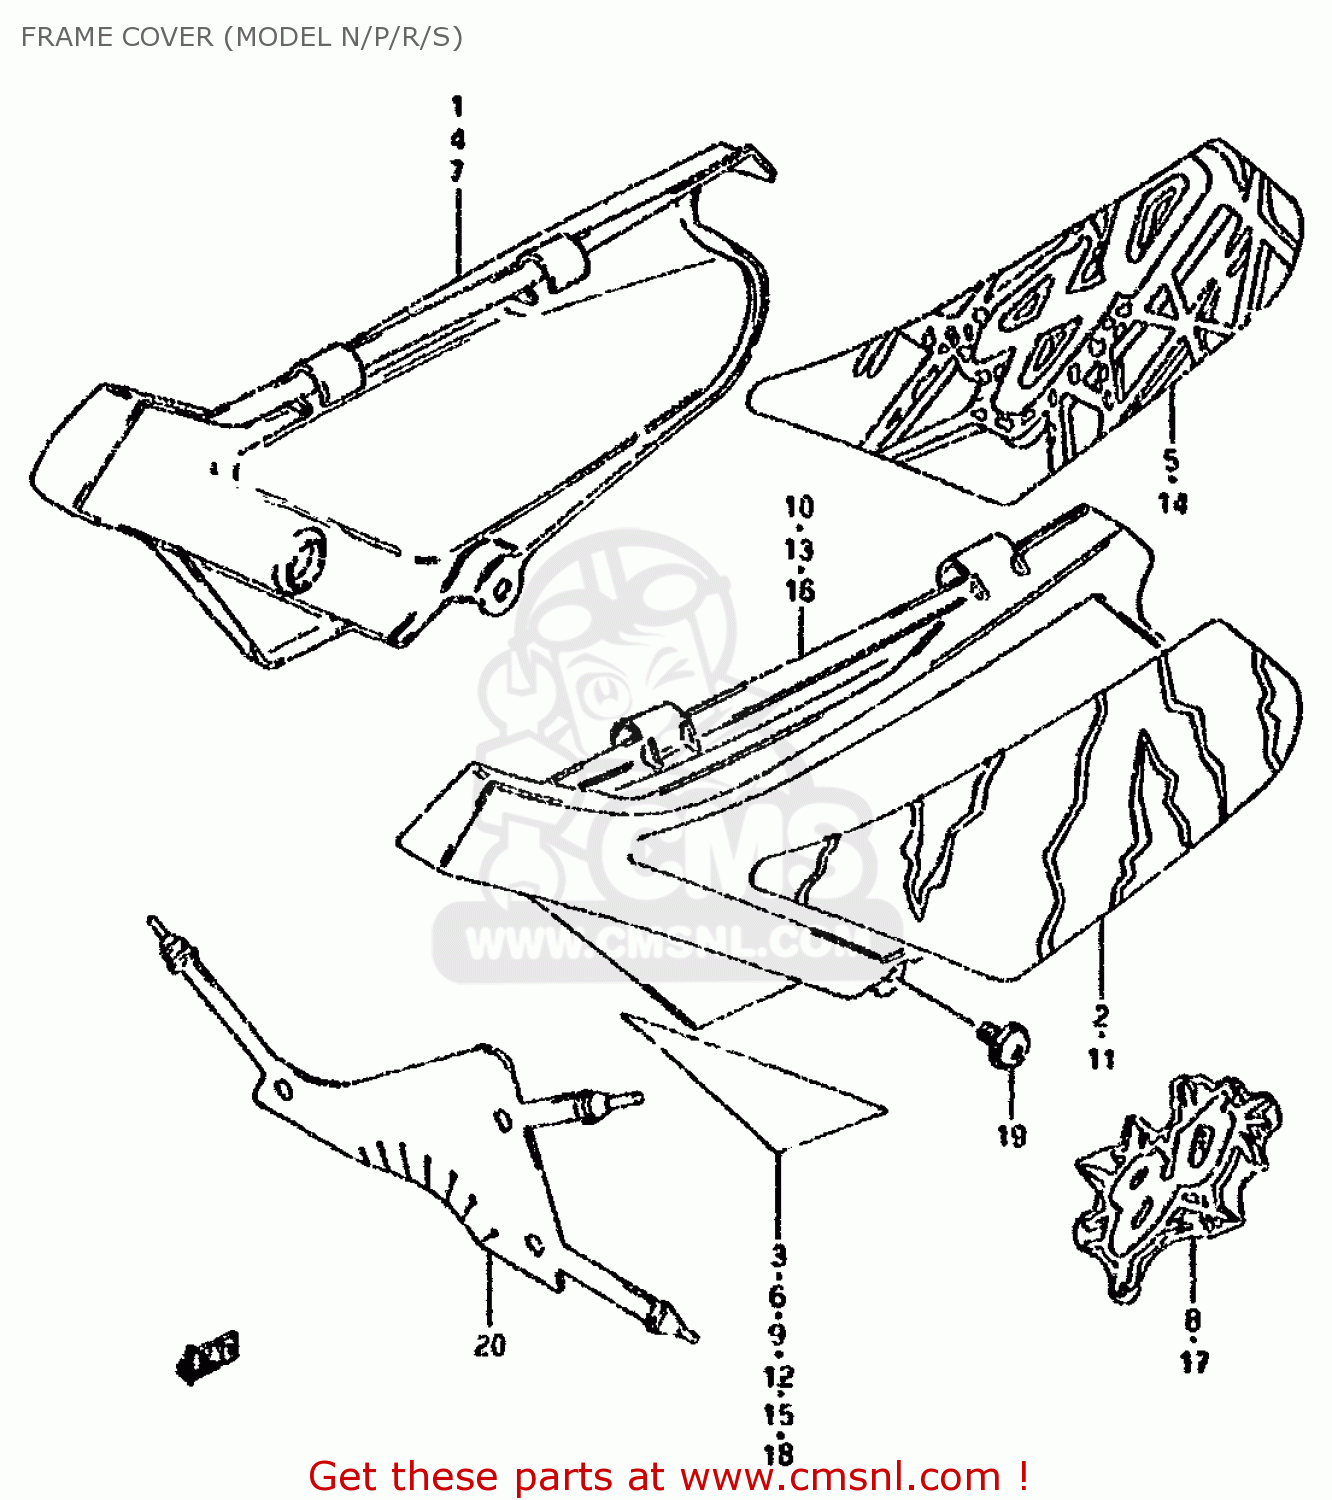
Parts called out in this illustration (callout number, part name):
1	COVER,FRAME,RIGHT
2	TAPE,FRAME COVER,RIGHT
3	TAPE,FRAME COVER NO.2,R
4	COVER,FRAME,RIGHT
5	TAPE,FRAME COVER,RIGHT
6	TAPE,FRAME COVER NO.2,R
7	COVER,FRAME,RIGHT
8	EMBLEM,FRAME COVER
9	TAPE,FRAME COVER NO.2,R
10	COVER,FRAME,LEFT
11	TAPE,FRAME COVER,LEFT
12	TAPE,FRAME COVER NO.2
13	COVER,FRAME,LEFT
14	TAPE,FRAME COVER,LEFT
15	TAPE,FRAME COVER NO.2
16	COVER,FRAME,L(WHITE)
17	EMBLEM,FRAME COVER
18	TAPE,FRAME COVER NO.2
19	SCREW(6X16)
20	WASHER(6.5X16X1.2)
21	MUD GUARD,FRAME COVER
